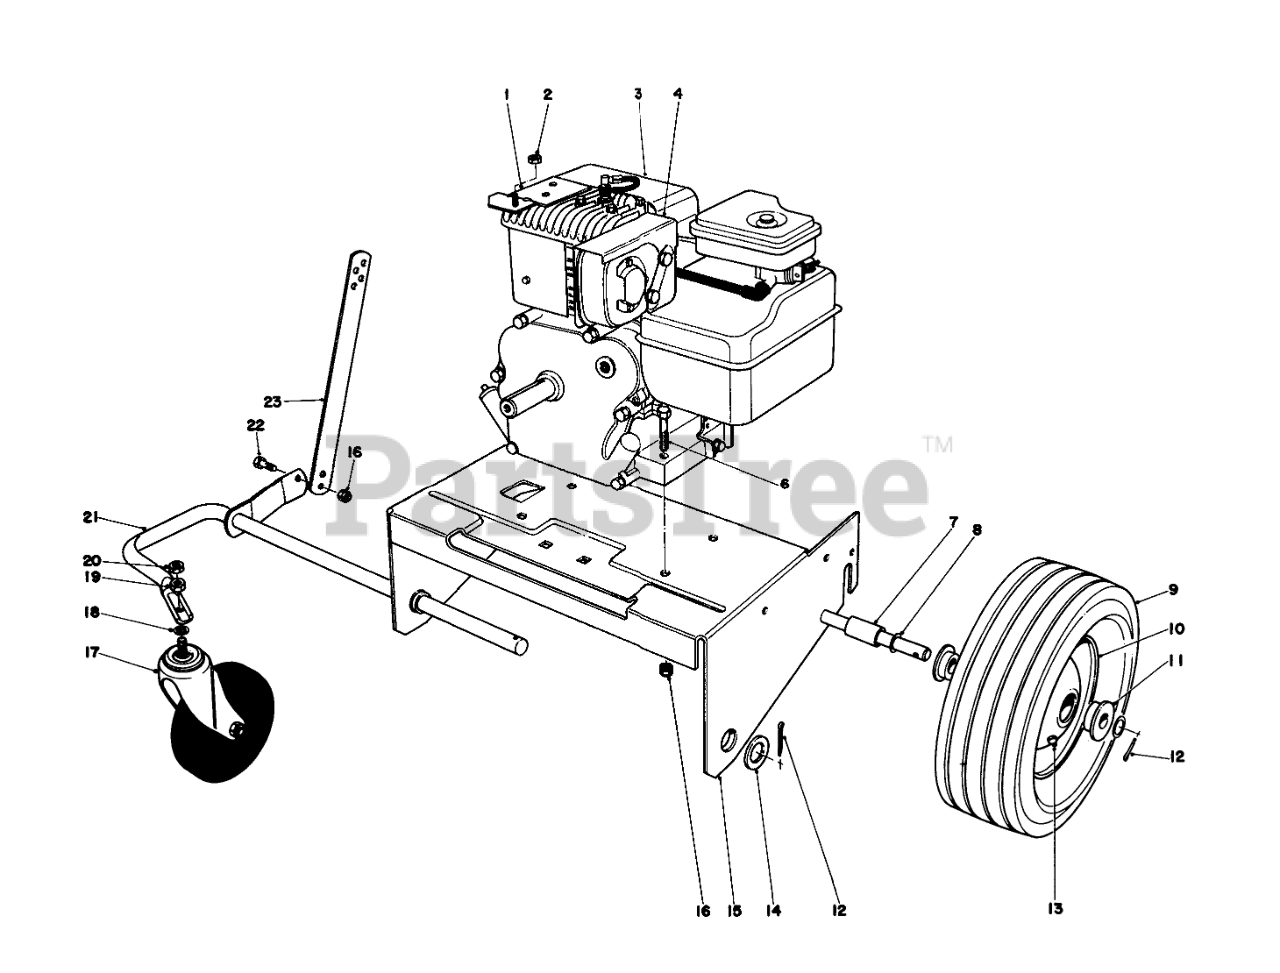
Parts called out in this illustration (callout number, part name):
1	MTG BRKT WA B
2	NUT-LOCK, NI
3	Engine
4	HEAT SHIELD
6	SCREW-HH
7	SPACER-AXLE
8	WASHER
9	3.50X10 SEMIPNEU TIRE
10	Wheel & Tire Assembly (Incl. Ref, #9, 11 & 13)
11	BUSHING
12	PIN-COTTER
13	FITTING-GREASE
14	WASHER-FLAT
15	BLWR ENG MTG PLT WA
16	NUT-LOCK, CONE
17	CASTER
18	WASHER-LOCK/INT
19	NUT-HH
20	1/2-13 CONELOCK NUT
21	FRT WHL SUPPORT WA
22	SCREW-HH
23	HT ADJ BAR
